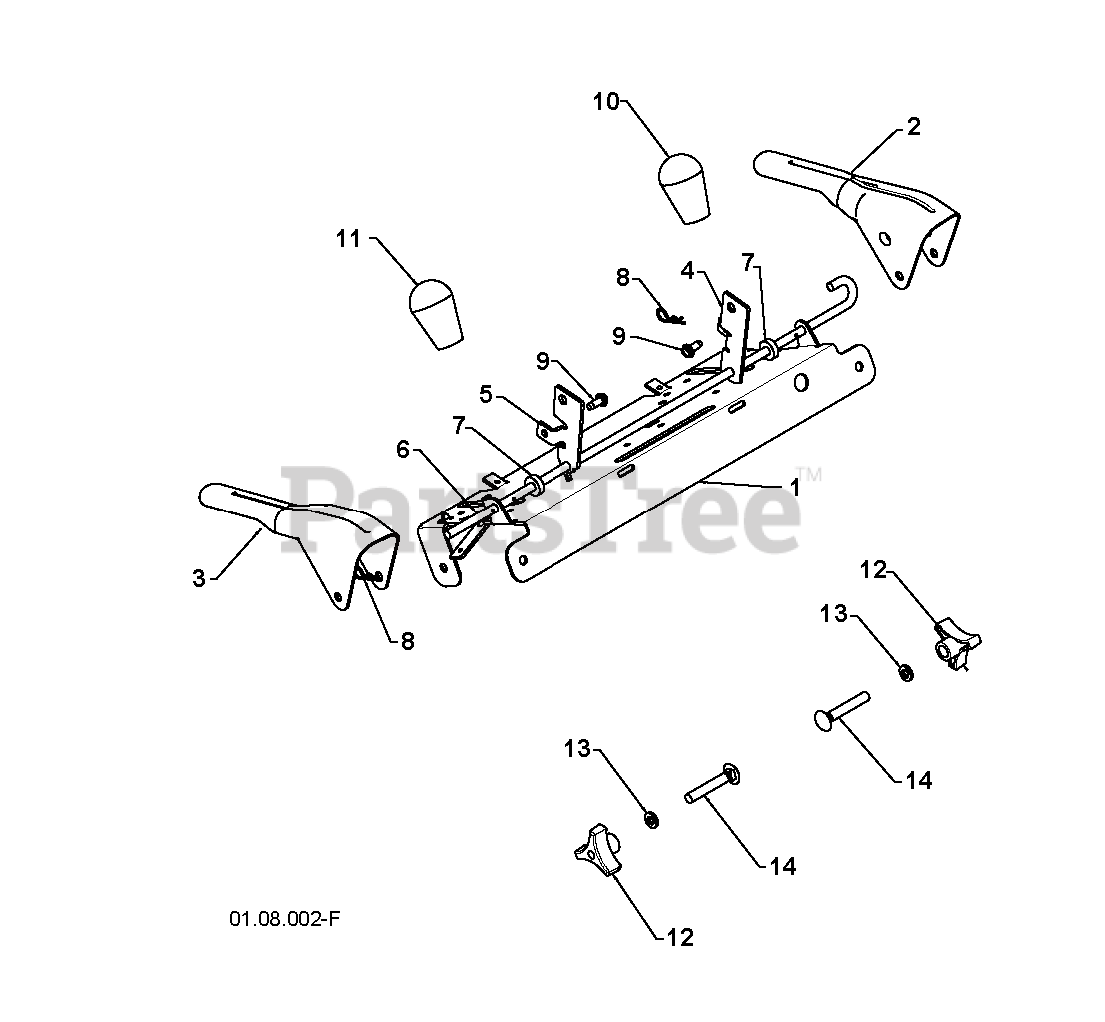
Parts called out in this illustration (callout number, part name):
1	PANEL.CONTROL.PNT.BLACK
2	RP.LEVER.CONTROL.LH.BLACK
3	CONTROLLEVERRH
4	ARM.TRACTION.ROD.YZ
5	ARM.IMPELLER.ROD.SNOW
6	BAIL.CONTROL.INTERLOCK
7	SPACER.CONTROL.LEVER
8	SPRING RETAINER
9	SCREW 14-20 X 5/8
10	KNOB LEVER, BLACK
11	RED KNOB SHIFTER
12	KNOB.HANDLE.3/8.TRI-POINT.BLAC
13	WASHER
14	BOLT 3/8-16 X 2-1/4
